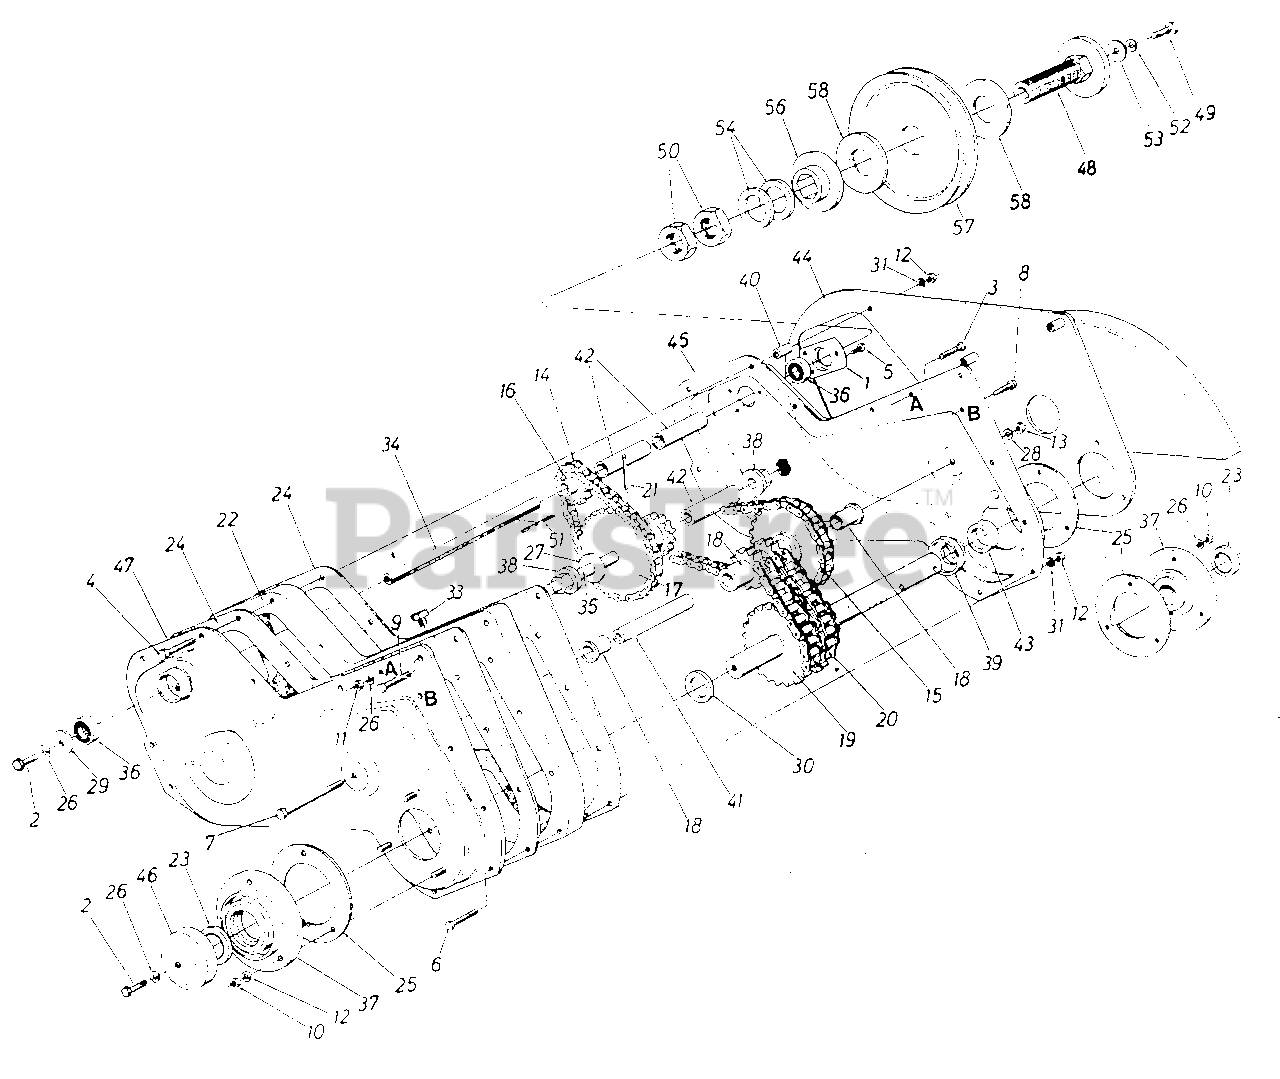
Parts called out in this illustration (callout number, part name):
1	Bearing Housing 1-3/8" Dia.
2	Hex Bolt 5/16-18 x .88" Lg. Spec.
3	Hex Bolt 5/16-18 x 1.50" Lg.
4	Hex Bolt 1/4-20 x 2.75" Lg.
5	Hex Wash. S-Tap. Scr. 1/4-20 x .50" Lg.
6	Hex Bolt i/4-20 x 1.50" Lg.
7	Hex Bolt 3/8-16 x 4.5" Lg.
8	Hex Wash. Hd. Bolt 1/4-20 x 1.5" Lg.
9	Hex Wash. TT-Tap Scr. 5/16-18 x 1.75" Lg.
10	HexCent. L.-Nut 5/16-18Thd.
11	Hex Nut5/16-18 Thd.
12	Hex Nut 1/4-20 Thd.
13	Hex Nut 3/8-16 Thd.
14	#41 Chain 1/2" Pitch x 34 Links-Endless
15	#42 Chain 1/2" Pitch x 48 Links-Endless
16	Sprocket 10 Tooth.500" Pitch
17	10 & 28 Teeth Sprocket Ass'y.
18	8-2 & 28 Sprocket Sleeve Ass'y
19	18-2 Sprocket Shaft Ass'y.
20	#50-2 Chain 5/8" Pitch x 28 Links-Endless
21	Spring Pin Spir. 1/4" Dia. x 1.50" Lg.
22	Spacer Block-Tiller Housing
23	Oil Seal Double Lip-1-1/4" Dia.
24	Gasket for Tiller Housing
25	Gasket for Brg.-Housing
26	L.-Wash. 5/16" I.D.
27	Fl.-Wash. .640" I.D. x 1.24" O.D.
28	L.-Wash. 3/8" I.D. Heavy Duty
29	Fl.-Wash. 344" I.D. x.1.125
30	Special Washer
31	L.-Wash. 1/4" I.D.
33	Vent Plug
34	Jack Shaft .525" I.D. x 7.78 " Lg.
35	Sprocket Shaft .63" Dia. x 5.0" Lg.
36	Ball Brg. .62" I.D. x 1.38" O.D.
37	Bearing Housing-1-1/4"
38	Hex Flange Brg.
39	Spacer 1.25" I.D. x 2.0" O.D.
40	Spacer .28" I.D. x .62" O.D. x .90" Lg.
41	Spacer .38" I.D. x .62" O.D. x 3.44" Lg.
42	Spacer.62" I.D. x .88" O.D. x 1.56" Lg.
43	Spacer 1.25" I.D. x 1.62" O.D. x . 50" Lg.
46	Dust Cap .320" Dia. Hole
49	Hex Bolt 5/16-18 x 1.25" Lg. Grade 5
50	Hex Jam Nut l.0-14 x 28 Thd.
51	Sq. Key 3/16 x 1.50" Lg.
52	L.-Wash. 5/16" I.D.
53	Fl.-Wash. .344" I.D. x 1.125" 0. D.
54	Spring Bell Wash. 1.0" I.D. x 2.0" O.D.
56	Floating Disc 3-1/4" O.D. x 1.0" I.D.
57	5/8 V-Pulley 1.50" I.D. x 6.50"
58	Friction Pad 3-1/4" O.D. x 1-3/8" I.D.
